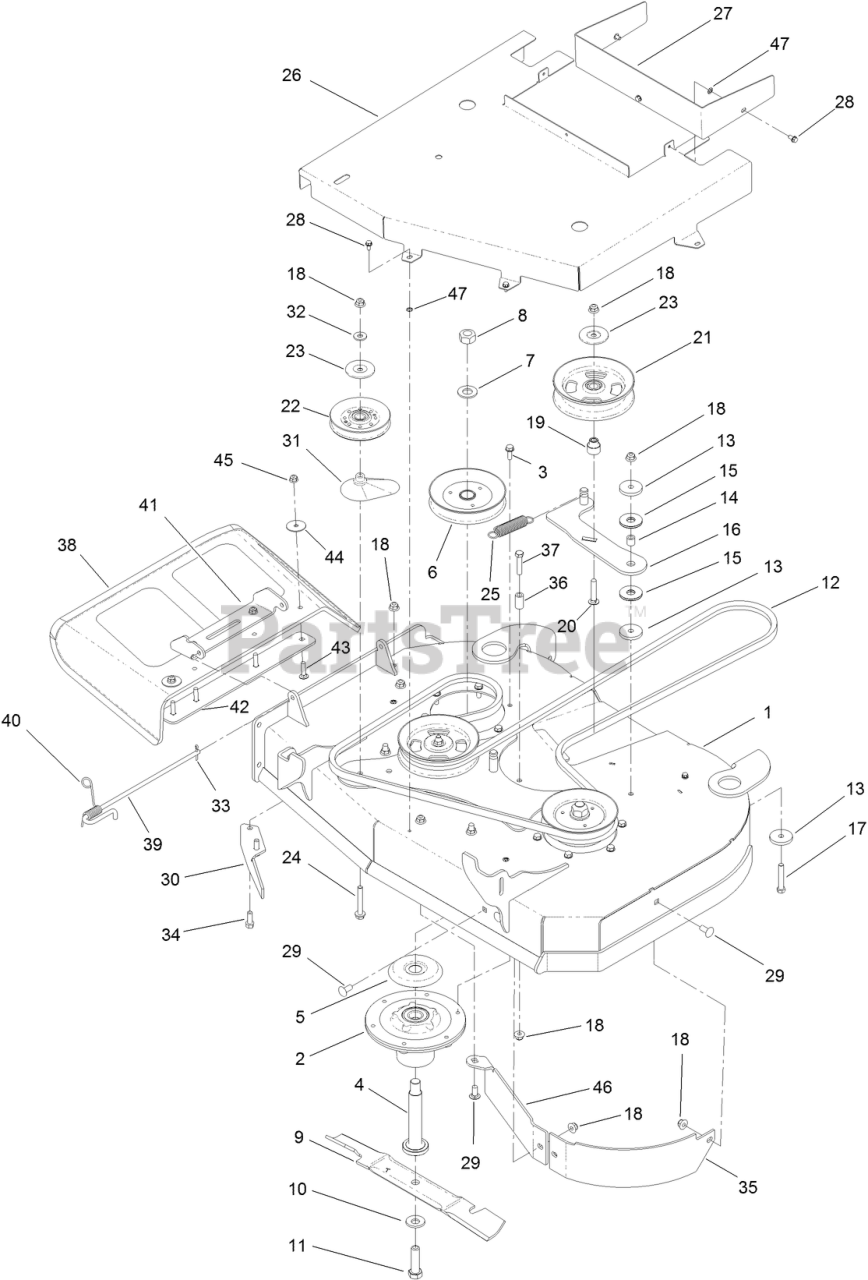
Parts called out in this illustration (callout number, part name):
1	36" DECK ASM-SERVICE
2	SPINDLE ASM
3	SCREW-TAPTITE
4	SHAFT-SPINDLE
5	SHIELD-BEARING
6	PULLEY
7	WASHER
8	NUT-HEX
9	BLADE - HI FLOW, 18.00 IN
10	WASHER-BELLEVILLE
11	SCREW-BLADE
12	BELT-V
13	WASHER-PLAIN
14	BUSHING-IDLER
15	WASHER-FRICTION, COMPOSITE
16	IDLER ARM ASM
17	SCREW-HH
18	NUT-HF, NI
19	BUSHING-IDLER
20	SCREW-CARR
21	PULLEY-IDLER, FLAT
22	IDLER - V 4.13 EOD-A
23	SHIELD-DUST
24	SCREW-HHF
25	SPRING-EXTENSION
26	GUARD-DECK,INTL
27	BRACKET-GUARD
28	SCREW-HWH
29	SCREW-CARR
30	BAFFLE-DISCHARGE
31	SPACER-PULLEY
32	WASHER-HARDENED
33	PIN-COTTER
36	SPACER-FENDER
37	SCREW-HH
38	DEFLECTOR
39	PIN-CHUTE
40	SPRING-TORSION
41	BRACKET UPPER, DEFLECTOR
42	PLATE-DEFLECTOR
43	SCREW-CARR
44	WASHER-FLAT
45	NUT-HF, NI
46	PLATE-DEFLECTOR
47	NUT-RETAINING
